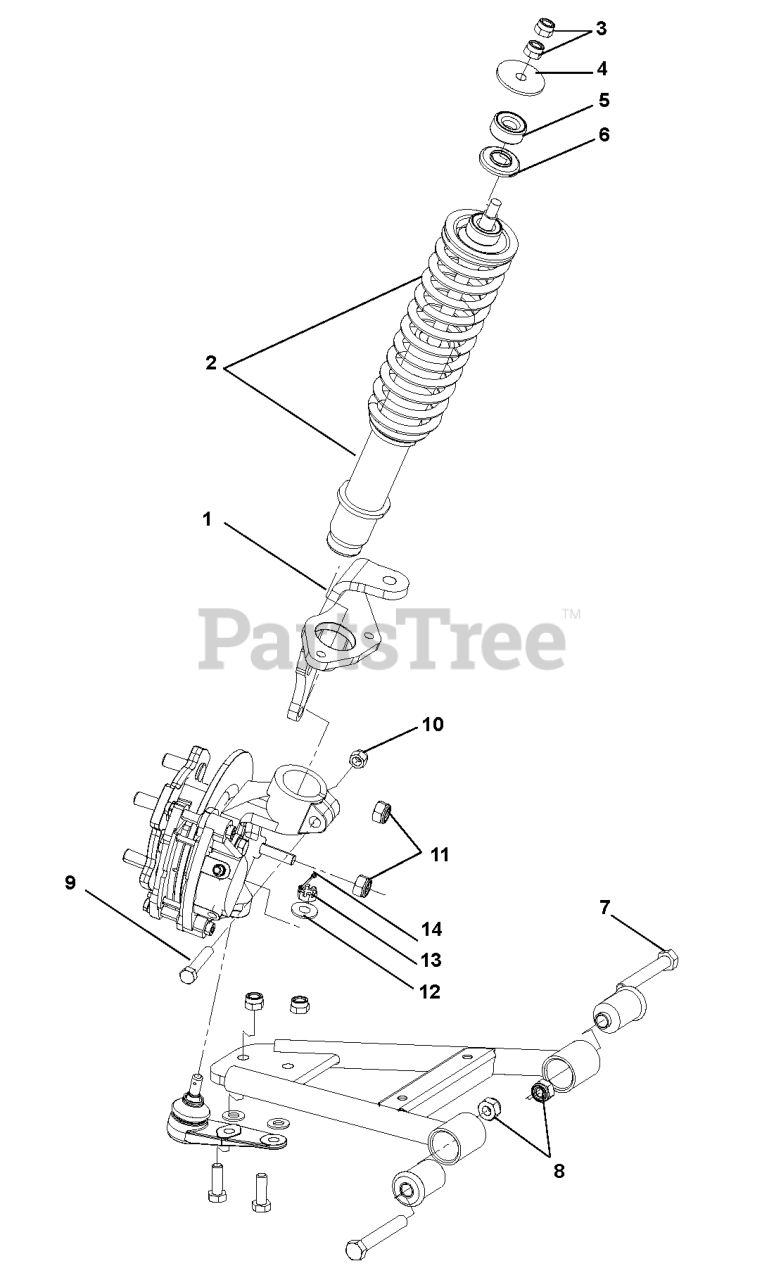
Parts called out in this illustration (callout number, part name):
1	STEERING BRACKET RIGHT
2	STRUT/COIL SPRING
3	NUT HEX JAM M10X1,25 6MTHK YLW
4	WASHER FLT 1.92ODX.413IDX.118T
5	GROMMET, RUBBER MOUNT
6	WASHER, STRUT MOUNT
7	HHCS M12X1.75X80 GR8.8 PLT
8	@NUT-LK-NYL M12-1.75 YWZC
9	BLT-HEX .38-16X2.00 GR8 YWZC
10	@NUT-LK-NYL .38-16 YWZC
11	NUT-LK-NYL M10-1.5 YWZC
12	@WSHR-FL-STL.438X1.00X.083 YWZ
13	NUT-HEX-SLOTTED M10-1.25 YWZC
14	@PIN-CTR .09X1.00 EXTPRSQCT YZ
